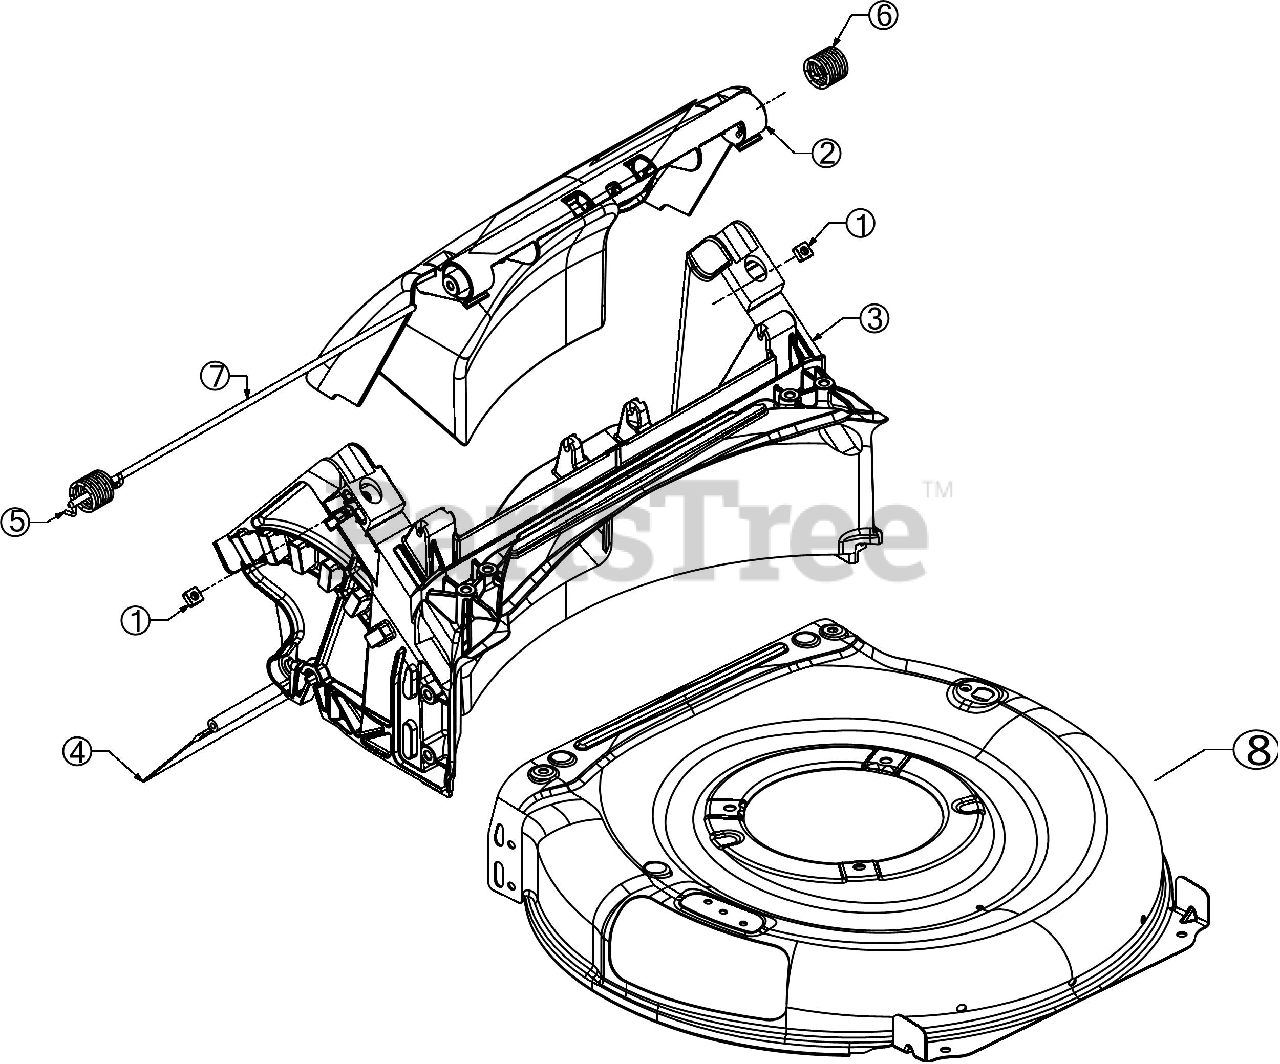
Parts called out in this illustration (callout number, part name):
1	SQUARE NUT 1/4-20
3	DOOR ASSEMBLY
4	TRAILSHIELD
5	TORSION SPRING (RH)
6	TORSION SPRING (LH)
7	REAR DOOR PIVOT ROD
8	21" DECK (2N1)
